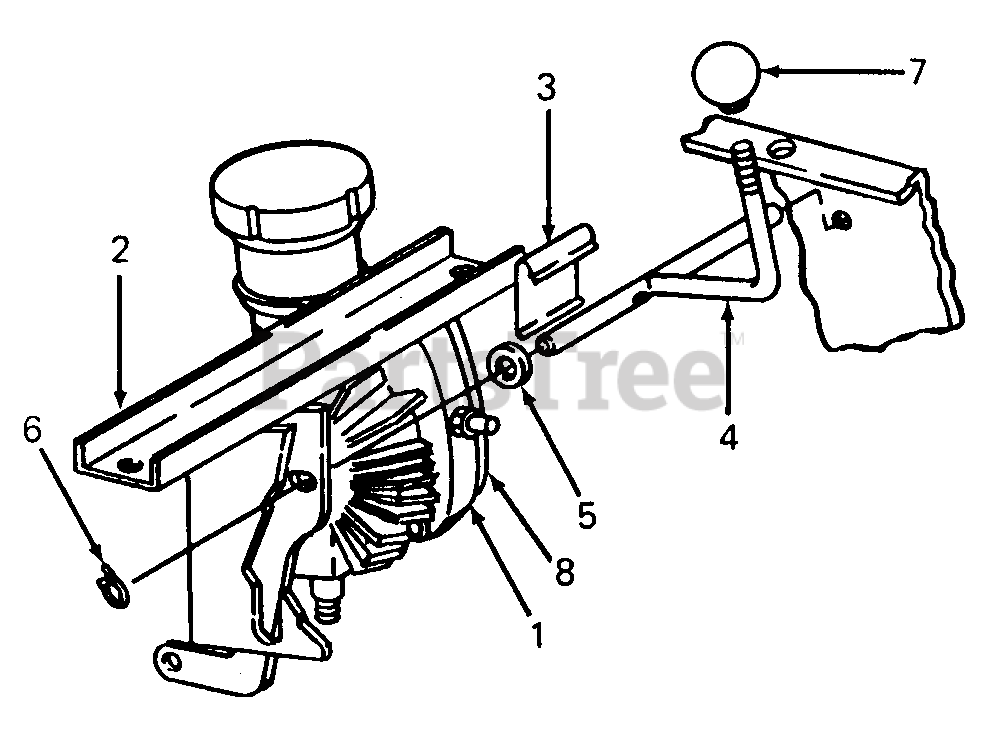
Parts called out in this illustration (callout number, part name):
1	Transmission, Hydro
2	Support, Transaxle
3	Lever, Dump
4	Lever, Dump
5	Washer, .344 X .88 X .06
6	Pin, 1/2 Int. Cotter
7	Knob, Ball
8	Gasket, Hydro Transmission
